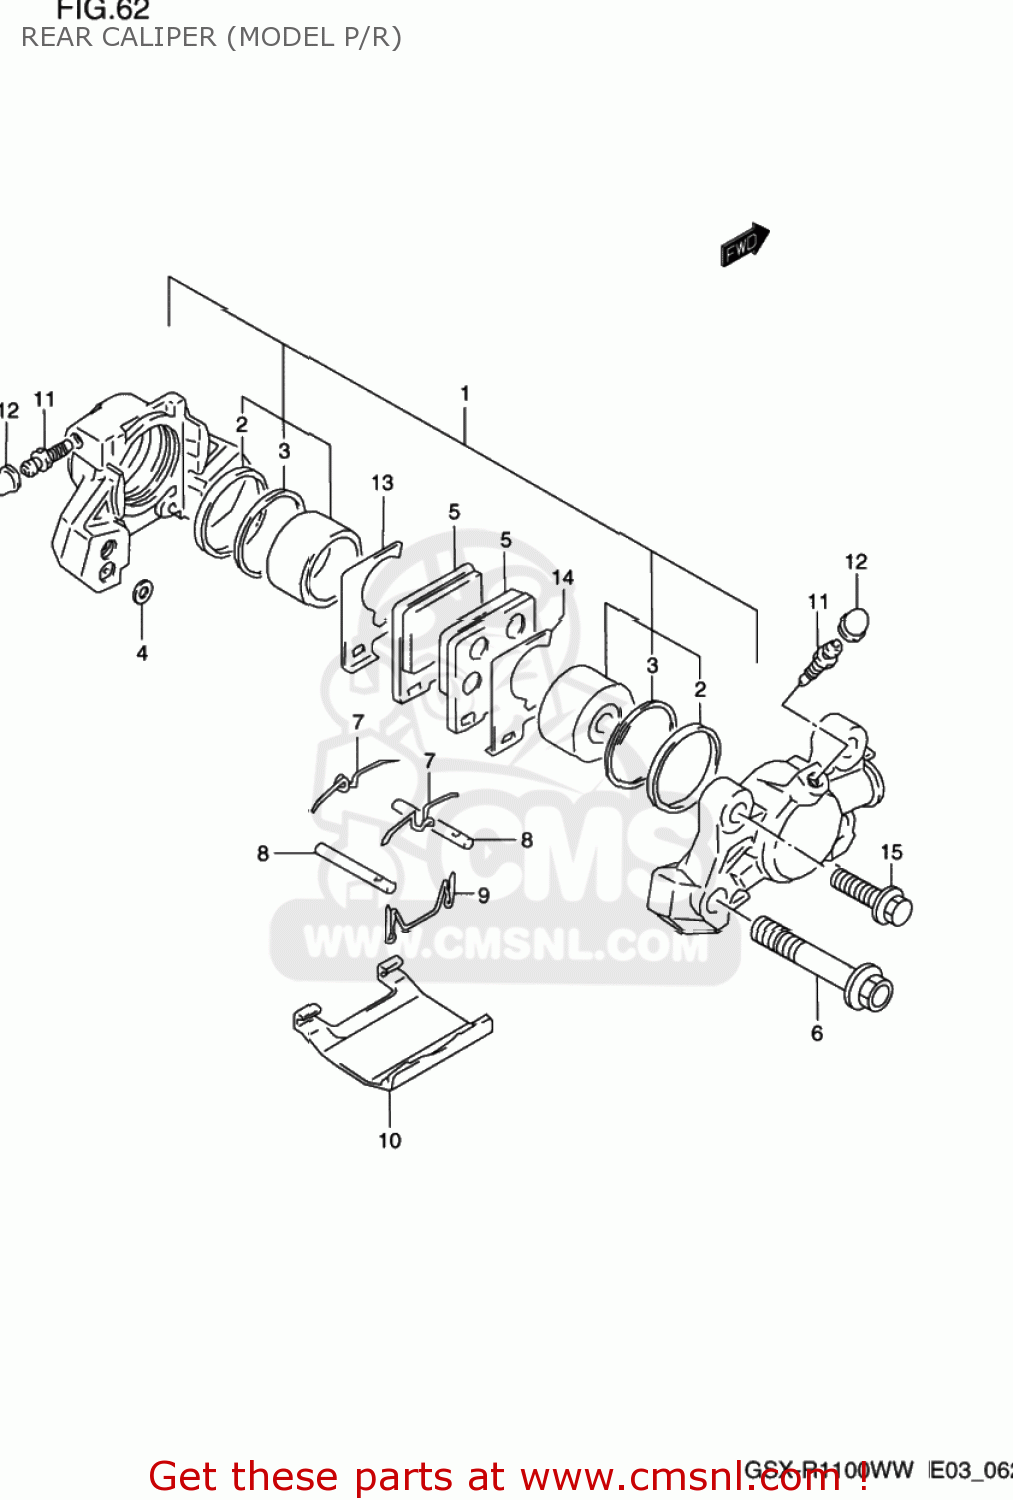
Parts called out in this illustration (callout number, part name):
1	PISTON SET
2	SEAL,PISTON
3	SEAL,WIPER
4	SEAL,JOINT
5	PAD,BRAKE
6	BOLT
7	SPRING
8	PIN,PAD
9	CLIP,PAD PIN
10	COVER
11	BLEEDER
12	CAP,BREATHER
13	SHIM,INNER
14	SHIM,OUTER
15	BOLT
